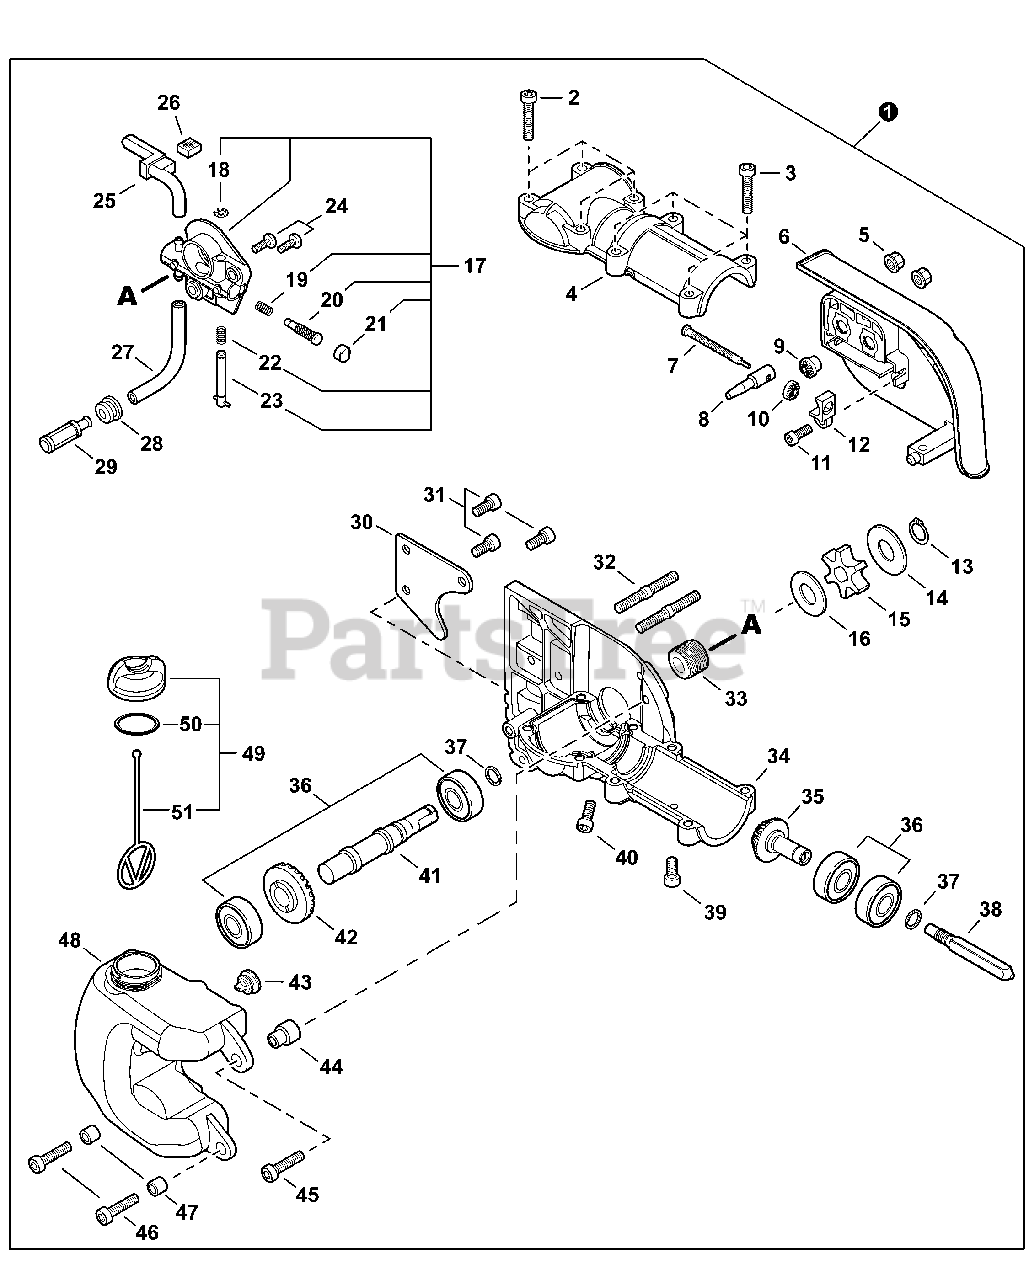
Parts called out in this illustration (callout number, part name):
1	GEAR CASE ASSY
2	SCREW M5x25
3	BOLT 5x25
4	CASE, GEAR - UPPER 35
5	NUT, FLANGE M6
6	GUARD, SPROCKET
8	TENSIONER, CHAIN
9	GEAR - 14 TOOTH
10	GEAR - 14 TOOTH
11	SCREW 4
12	COLLAR 8
13	RING, SNAP
14	WASHER 10
15	SPROCKET, DRIVE
16	WASHER 10.2x24.5x1.2
17	AUTO-OILER ASSY
20	PLUNGER ASSY
21	CAP, PLUNGER
23	ADJUSTER, OILER
24	SCREW 5x10
25	PIPE, OIL OUTLET
26	PAD, FOAM
27	PIPE 3x6x70
28	GROMMET
29	FILTER, OIL
31	SCREW 5x10
32	BOLT, STUD 6
33	GEAR, WORM
34	CASE, GEAR
35	GEAR, BEVEL - 15 TOOTH
36	BEARING, BALL
37	RING, SNAP 12
38	CONNECTOR, DRIVESHAFT
39	BOLT M5x10
40	SCREW 5x10
41	SHAFT, GEAR
42	GEAR, BEVEL - 23 TOOTH
43	VENT ASSY
44	COLLAR 6
45	SCREW M5x25
46	BOLT 5x20
47	SPACER 6.2x7.8x6
48	TANK, OIL
49	CAP ASSY
50	O-RING 18
51	CONNECTOR, CAP L= 60 MM
